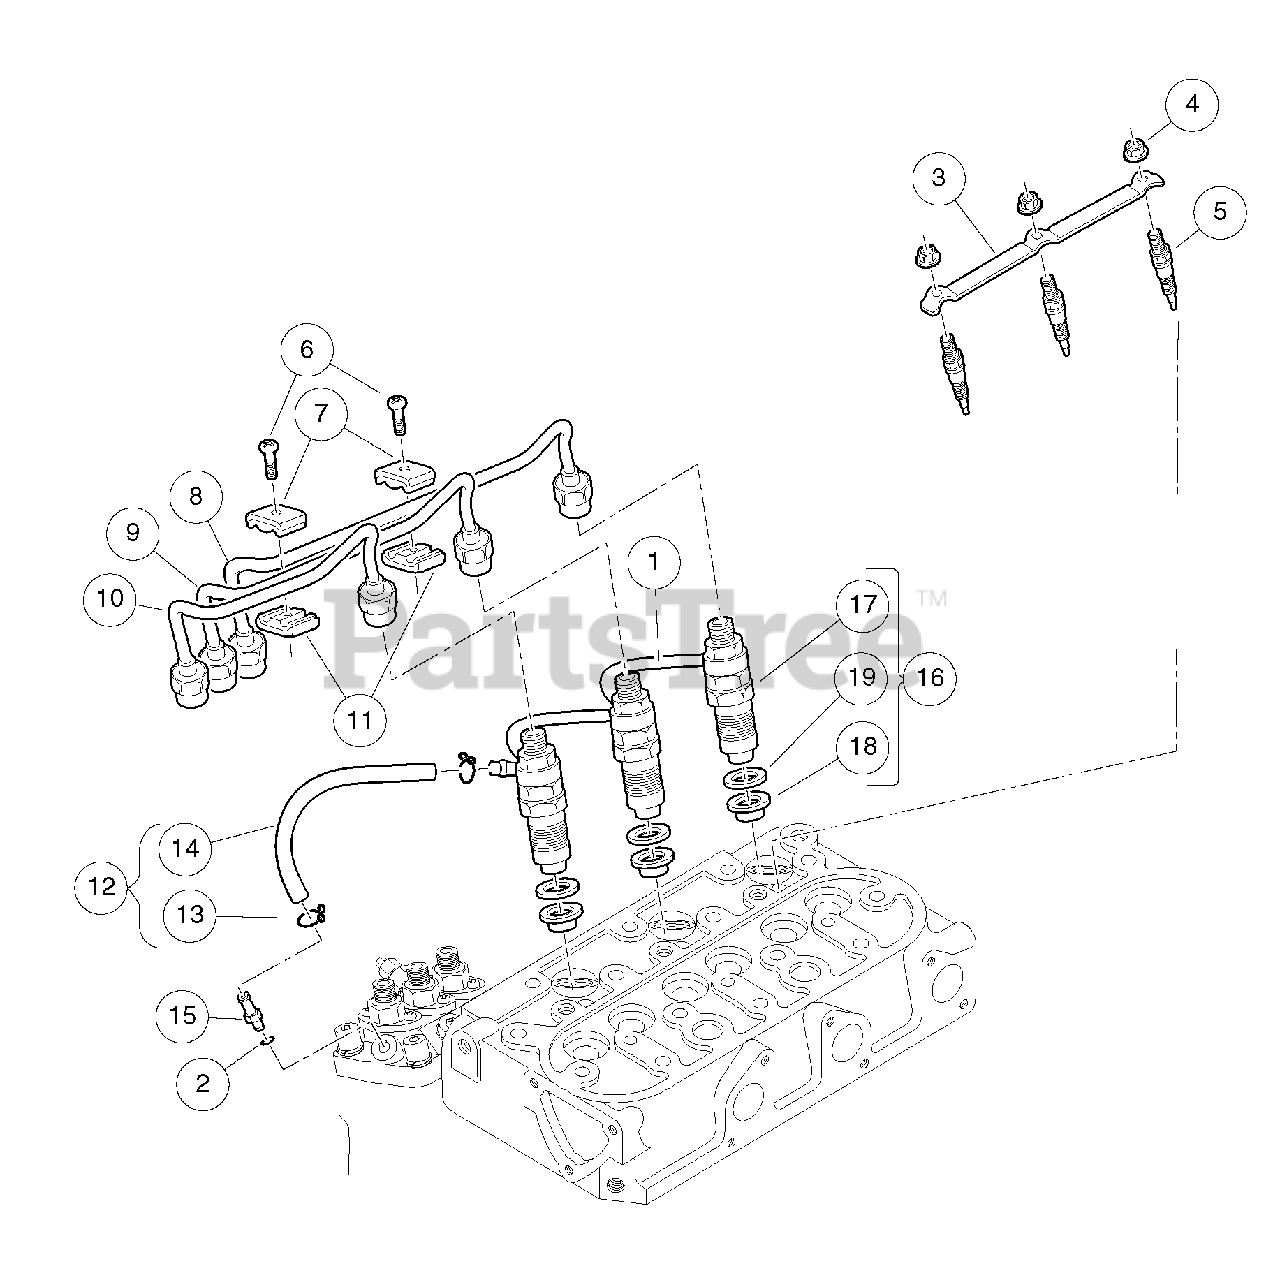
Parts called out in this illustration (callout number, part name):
1	Assy Pipe, D722 Fuel Over Flow
2	Gasket, 6 X 10
3	Cord, Glow Plug
4	Nut, Flange,m4
6	Screw, Washer
7	Clamp, Pipe, Top
8	Pipe, Injection, Left
9	Pipe, Injection, Right
10	Pipe, Injection, Middle
11	Clamp, Pipe, Bottom
12	Assy Pipe, Over Flow
13	Clip, Pipe, Return
14	Hose, Overflow
15	Screw, Air Bleeder
16	Kit, Holder, Nozzle
17	Assembly, Nozzle Holder
18	Seal, Heat
19	Gasket, Nozzle
